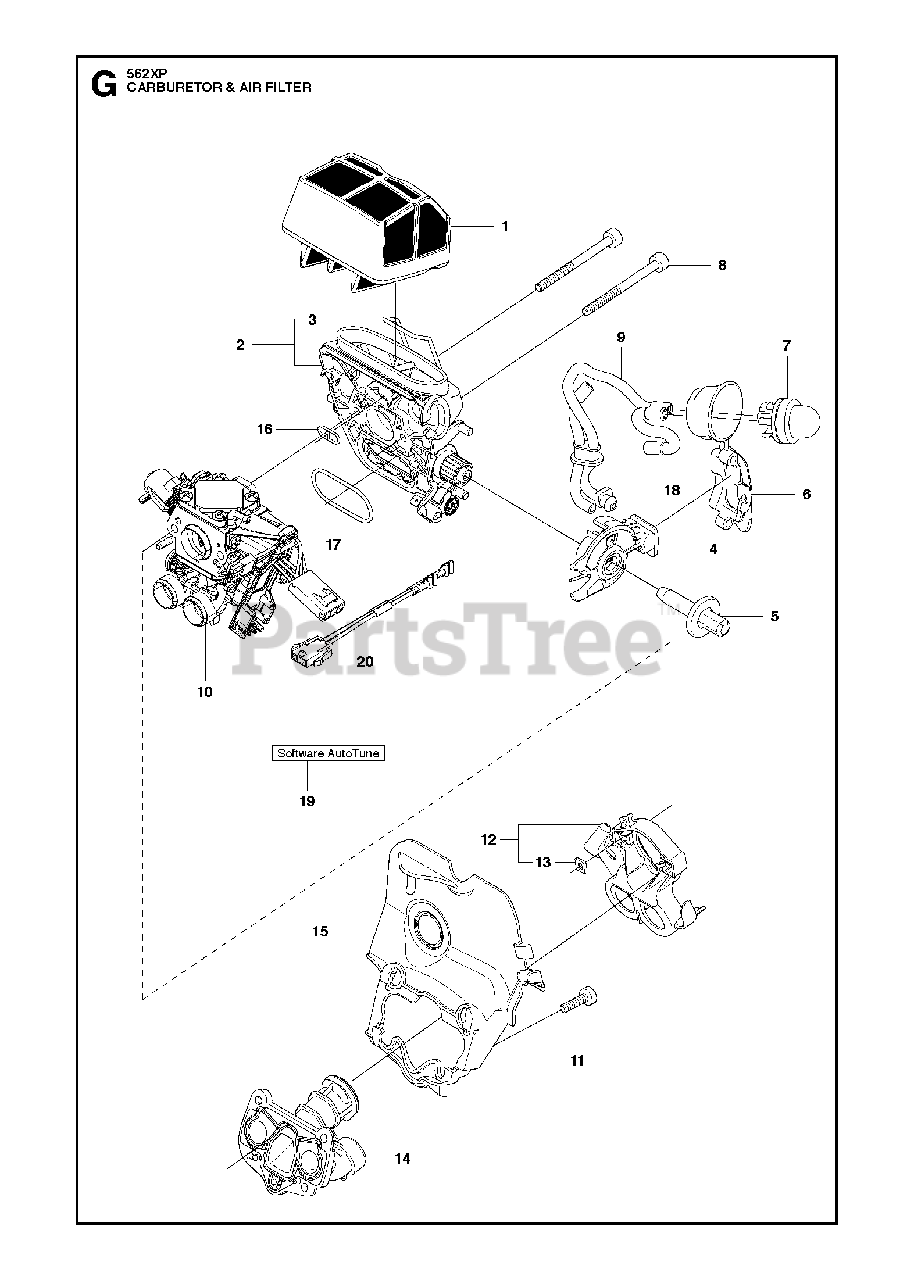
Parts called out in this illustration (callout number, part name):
1	AIR FILTER ASSY BLCK 80 MICRON
1	AIR FILTER ASSY YLLW 44 MICRON
1	AIR FILTER ASSY NATURAL FELT
2	FILTER HOLDER ASSY
3	SHACKLE
4	CHOKE CONTROL ASSY
7	AIR PURGE BUBBLE
9	FUEL HOSE
10	RP CARBURETOR
11	SCREW IHSCM
13	NUT
14	RP INLET PIPE
15	INTERMEDIATE WALL
19	Husqvarna TBD
20	WIRING ASSY
